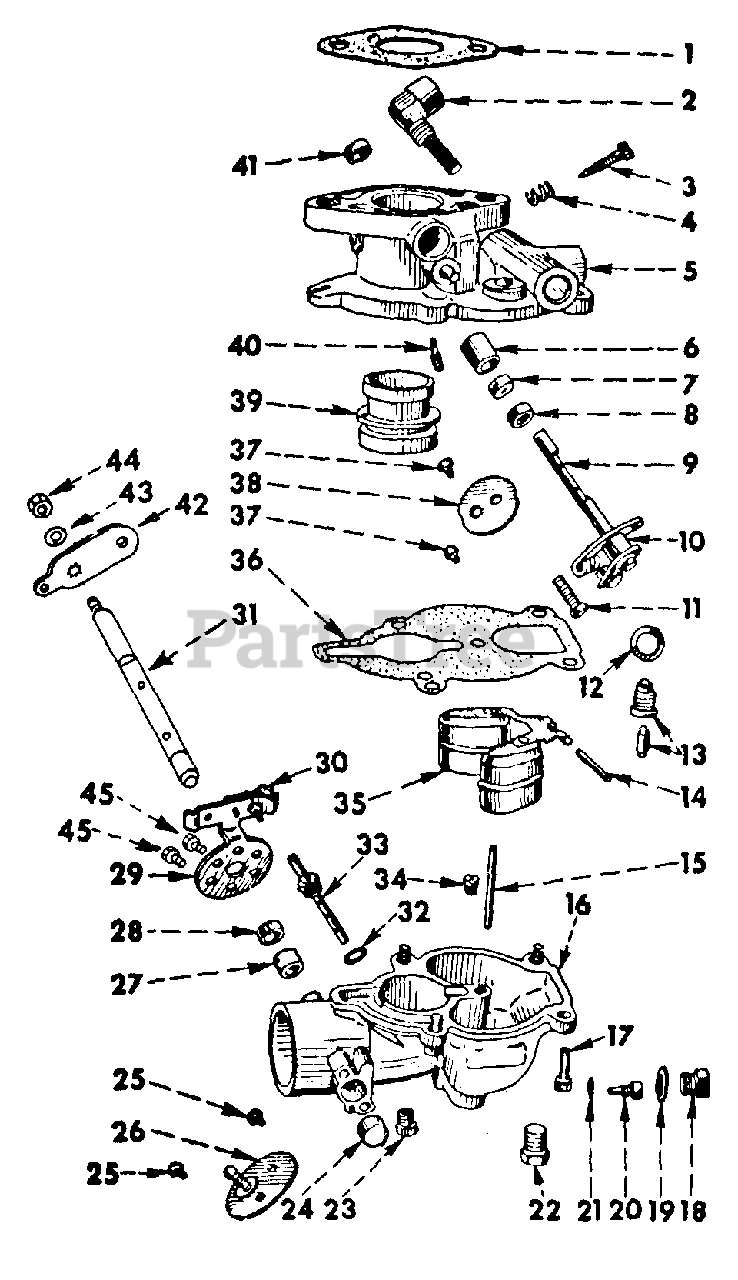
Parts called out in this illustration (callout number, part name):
1	GASKET, CARBURETOR
2	ELBOW AND STRAINER ASSY
3	NEEDLE, IDLE ADJUSTING SCREW
4	SPRING, IDLE ADJUSTING NEEDLE VALVE SCREW
5	BODY
6	BUSHING, THROTTLE
7	SEAL, THROTTLE SHAFT
8	RETAINER, THROTTLE SHAFT SEAL
9	LEVER AND SHAFT W/SCREW ASSY, THROTTLE LEVER
10	PIN, THROTTLE LEVER TAPER
11	SCREW, 8-36 X 5/8 C-Z SLT-HEX HD MACH
12	WASHER, FUEL VALVE SEAT
13	VALVE AND SEAT ASSY, FUEL
14	AXLE, FLOAT
15	TUBE
16	BOWL
17	SCREW W/WASHER, 10-32 X 5/8 ZND SLT-FIL HEAD MACH
18	PLUG, LOWER
19	WASHER, MAIN PASSAGE PLUG
20	JET, MAIN
21	WASHER, MAIN JET
22	PLUG, 1/8-27 AUTO HEX-HD PIPE DRAIN
23	FILTER ASSY, DRIP PLUG
24	PLUG, CHOKE SHAFT HOLE
25	SCREW ASSY, CHOKE VALVE PLATE
26	PLATE ASSY, CHOKE LEAVE
27	WASHER, CHOKE SHAFT PACKING
28	RETAINER, CHOKE SHAFT PACKING
29	BRACKET ASSY, CHOKE VALVE
30	CLAMP, CHOKE VALVE BRACKET
31	SHAFT, CHOKE
32	WASHER, DISCHARGE JET FIBRE
33	JET ASSY, DISCHARGE
34	JET WELL VENT
35	FLOAT ASSY
36	GASKET, BOWL TO BODY
37	SCREW ASSY, THROTTLE VALVE PLATE
38	PLATE THROTTLE VALVE
40	JET, IDLING - REPLACES IH-68550-C1
41	PLUG, THROTTLE SHAFT HOLE
42	LEVER, CHOKE SHAFT
43	WASHER, CHOKE SHAFT LEVER
44	NUT, CHOKE SHAFT LEVER
45	SCREW, 8-32 X 5/8 SLT-FIL-HD MACH
